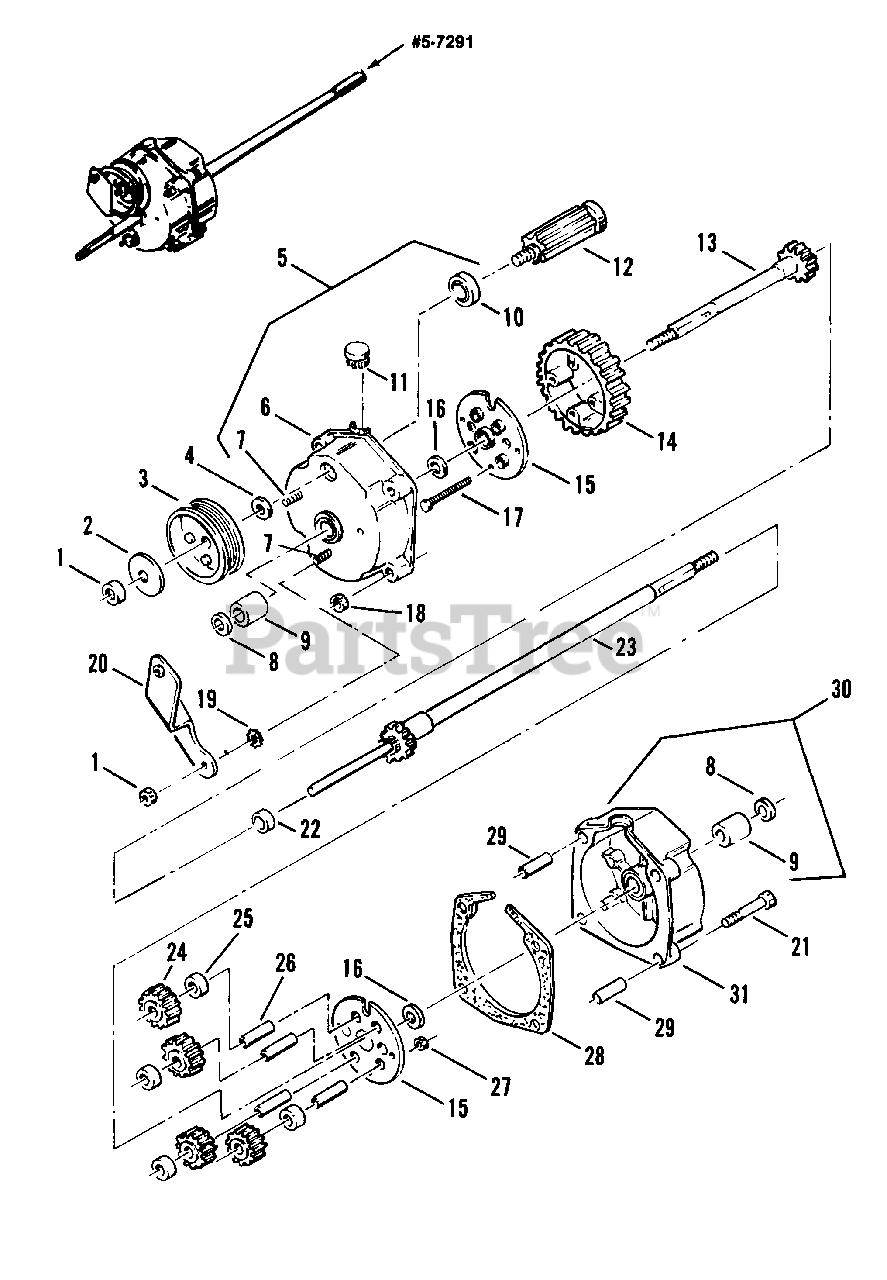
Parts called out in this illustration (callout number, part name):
1	NUT, 5/16-24 Hex Lock
2	WASHER, Spring
3	PULLEY, Poly-Vee Belt
4	WASHER, Spring
5	HOUSING ASSEMBLY, Right
6	HOUSING, Right Side
7	SCREW, 5/16-24 x 1-1/8 Rib Neck
8	SEAL, 5/8" ID
9	BEARING, Differential
10	BEARING, Ball
11	PLUG, Housing
12	GEAR, Input
13	AXLE, Short
14	GEAR, Differential, 46 Tooth
15	PLATE
16	WASHER, Thrust
17	SCREW, 10-32 x 1-1/2" Hex Head Cap
18	NUT, 1/4-28 Hex Lock
19	WASHER, 5/16" Internal External Tooth Lock
20	BRACKET, Differential
21	SCREW, 1/4-28 x 1-3/8 Hex Head Cap
22	SPACER, Axle Gear
23	AXLE, Long
24	GEAR, Pinion, 12 Tooth
25	SPACER, Pinion Gear
26	SHAFT, Pinion
27	NUT, 10-32 Hex Lock
28	GASKET, Housing
29	PIN, 3/8-7/16" Roll
30	HOUSING ASSEMBLY, Left
31	HOUSING, Left Side
